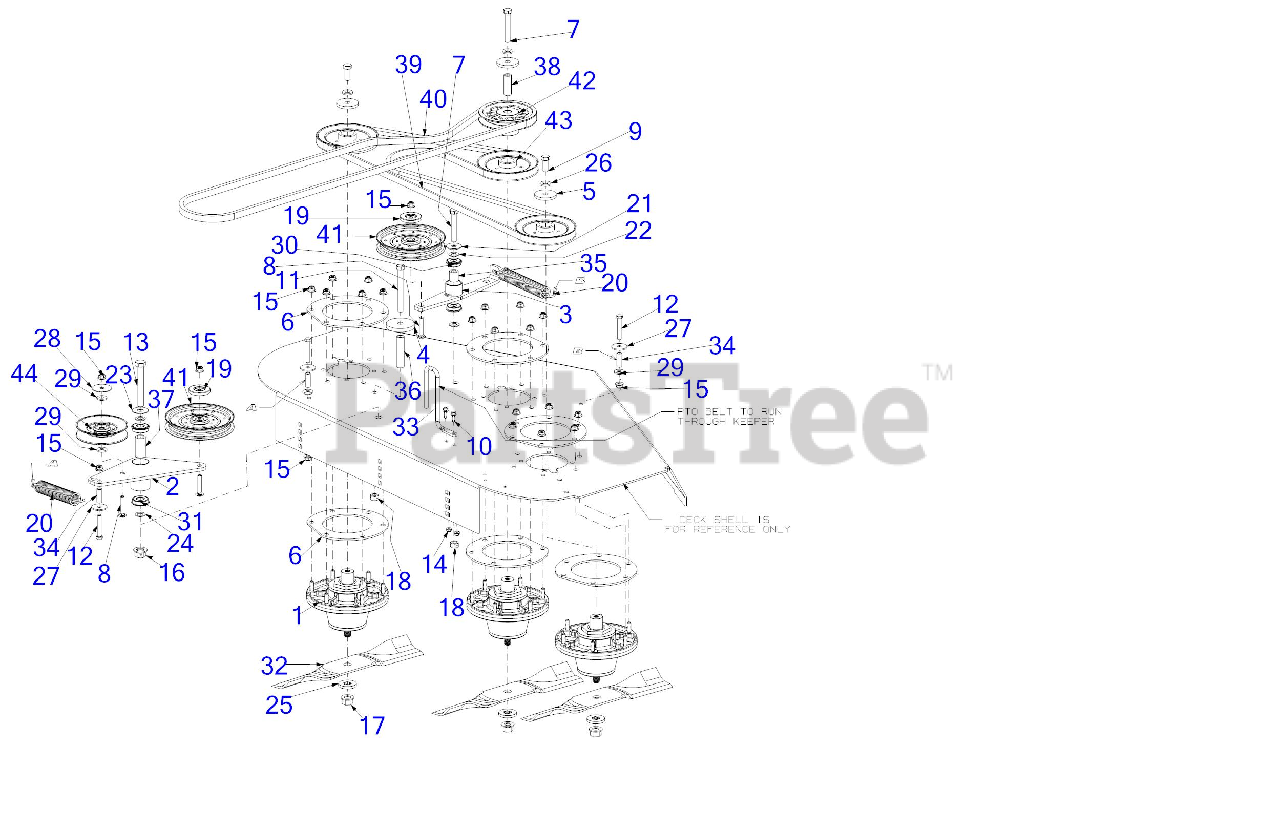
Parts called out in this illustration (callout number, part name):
1	SPINDLE ASSEMBLY
5	FLAT WASHER 0.531 X 2.125 X 0.25
6	SPINDLE SUPPORT BRACKET TOP/BTM
7	SCREW-HEX 1/2-13 X 3.00
8	CARRIAGE BOLT 3/8-16 x 2
9	SCREW 1/2-13 x 1.25 GR5
10	SCREW 1/4-20 x .75 GR5
11	SCREW 1/2-13 x 4.5 GR 5
12	SCREW 3/8-16 x 2.25 GR5
13	SCREW 5/8-18 x 4.25 GR5
14	FLANGE LOCK NUT
17	FLANGE NUT - 5/8-18 GDE 8
18	HEX NUT CTR LK 1/2-13
19	PULLEY CAP
20	EXTENSION SPRING
21	WASHER .51 x 1.5 x .07
22	FLAT WASHER .510 x 1.00 x .060
23	FLAT WASHER-.63IDX1.595ODX.62
24	FLAT WASHER
25	FLAT WASHER - SPECIAL
26	FLAT WASHER .531X1.060X.134
27	FLAT WASHER .406X1.500X.105
28	HUB CAP WASHER .406 x 1.92 x .060
29	FLAT WASHER .406ID X1.0 OD
30	ROLLER BEARING .5X1.37X.44
31	BALL BEARING
32	17" BLADE (HI LIFT)
35	SPACER 0.51 X 0.88 X 1.00
37	SPACER 0.63 X 1.00 X 2.01
38	SPACER 0.51 X 0.75 X 2.12
40	48" DECK PTO BELT B-SECT
41	IDLER PULLEY
42	DRIVE PULLEY
43	SPINDLE PULLEY 6"
44	IDLER PULLEY 5.06 OD
